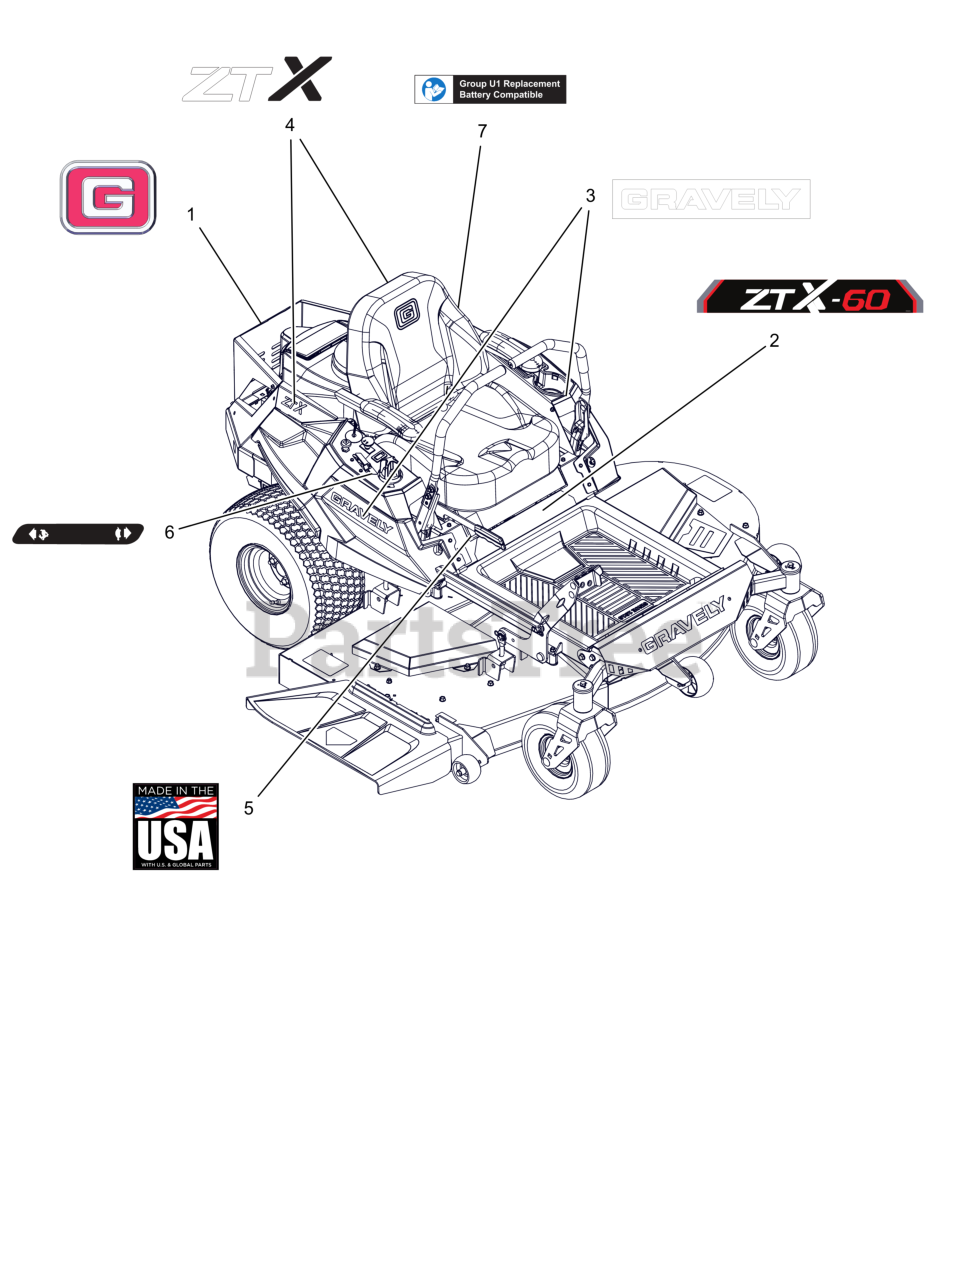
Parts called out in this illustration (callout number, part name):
1	DECAL, GRAVELY BRAND
2	DECAL, ZTX - 60"
3	DECAL, 9.5" GRAVELY LOGO
4	DECAL, REAR WRAP - ZTX
5	DECAL, MADE IN USA
6	DECAL, DASH DECAL
7	DECAL, U1 BATTERY REPLACEMENT
